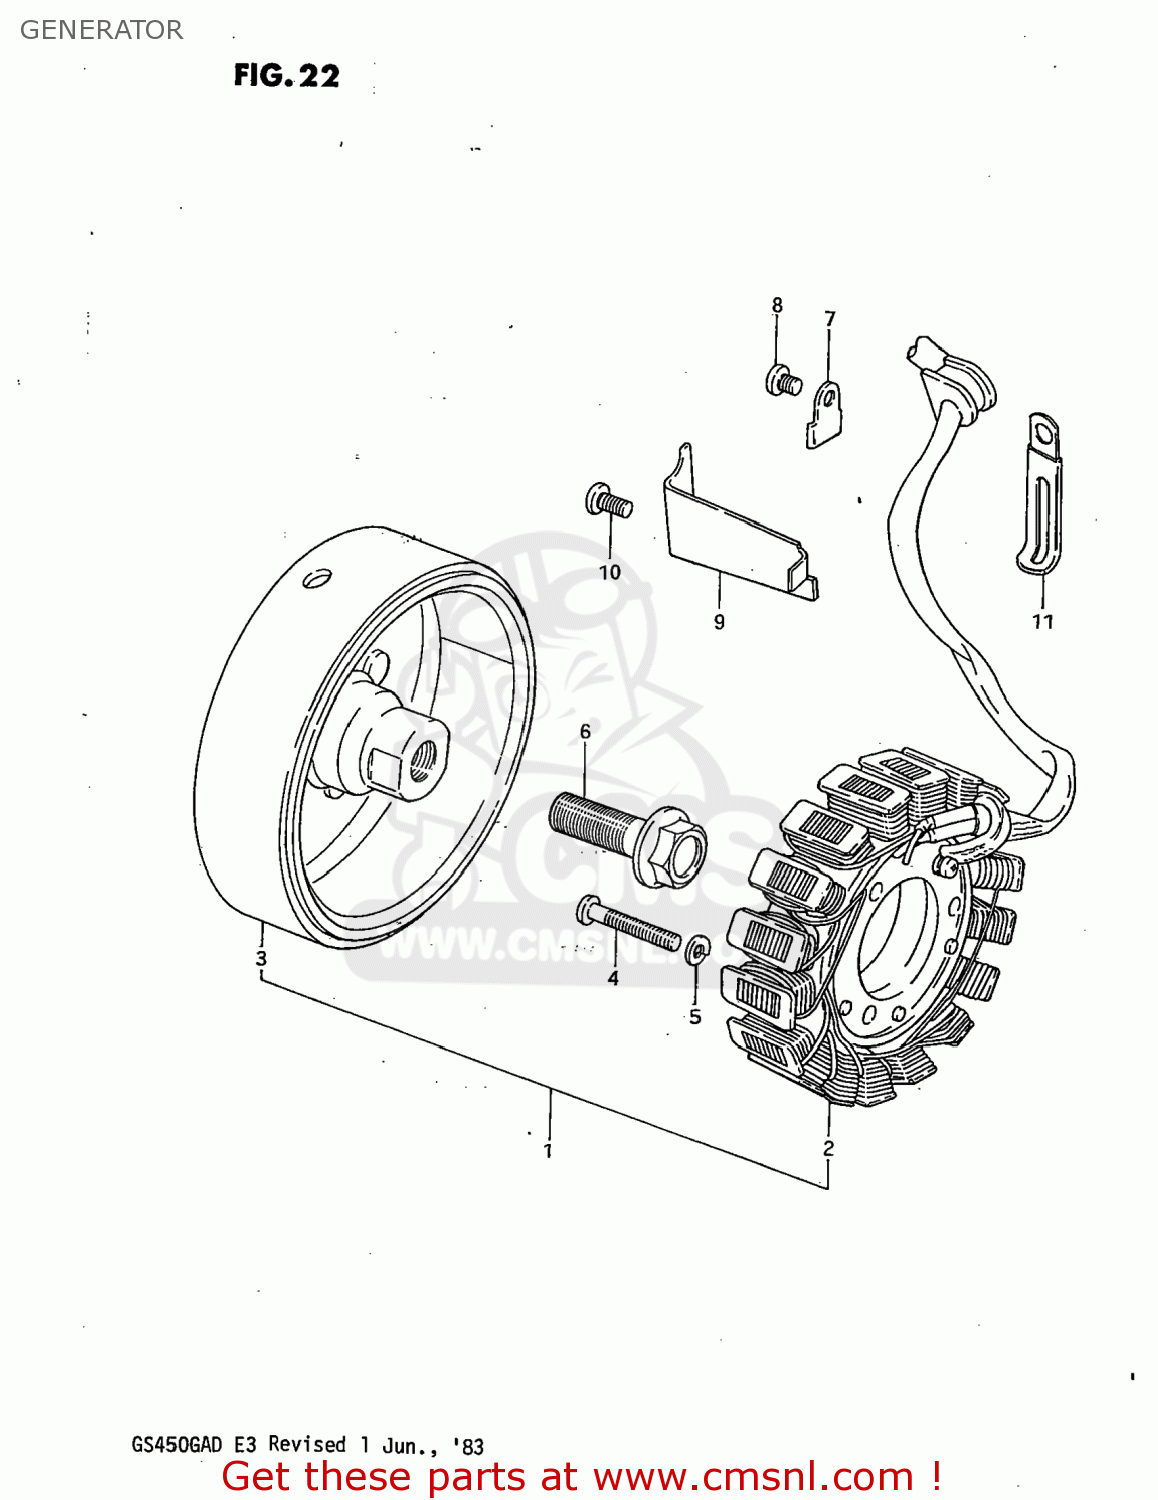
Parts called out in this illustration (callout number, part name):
1	GENERATOR ASSEMBLY
2	STATOR ASSEMBLY
3	ROTOR ASSEMBLY
4	SCREW
5	LOCK WASHER
6	BOLT(12X40)
7	CLAMP,GENERATOR LEAD WIRE
8	SCREW
9	CLAMP,GENERATOR LEAD WIRE
10	SCREW
11	CLAMP L:35
